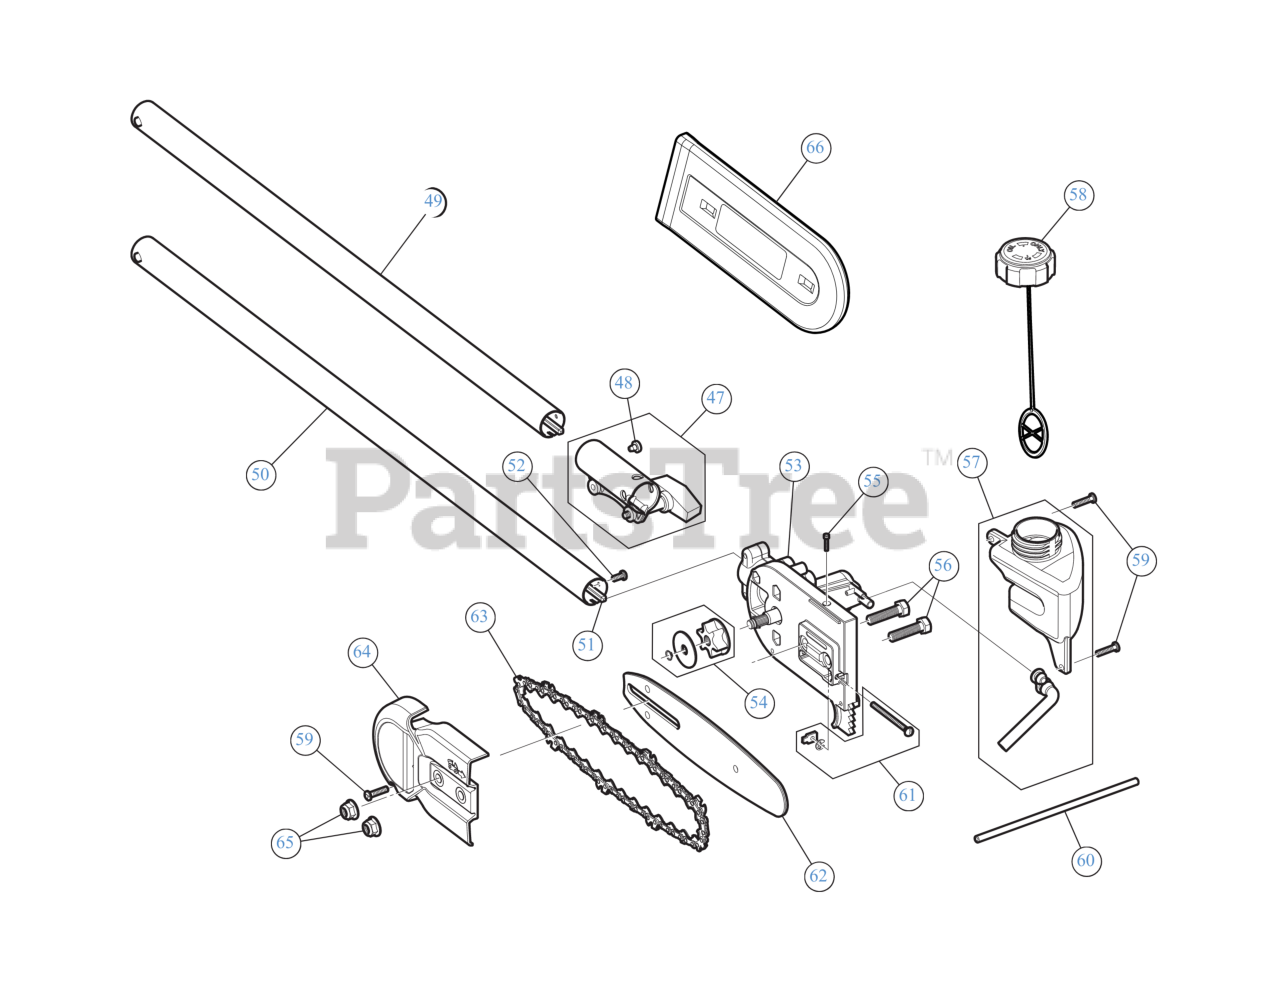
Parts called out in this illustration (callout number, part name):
49	Extension Boom
50	Lower Drive Shaft Housing
51	FLEXIBLE DRIVE SHAFT
52	SCREW 1/4-20 X.500
53	GEAR BOX ASSEMBLY
54	SPROCKET ASSEMBLY
55	SCREW 4X40X.50
56	SCREW 5/16-18 x 1.25 GR5
57	OIL TANK ASSEMBLY
58	FUEL CAP ASSEMBLY
59	SCREW, #8-16X.750 PH
61	CHAIN TENSION HDW
64	CHAIN GUARD
65	FLANGE LOCK NUT 5/16-18
